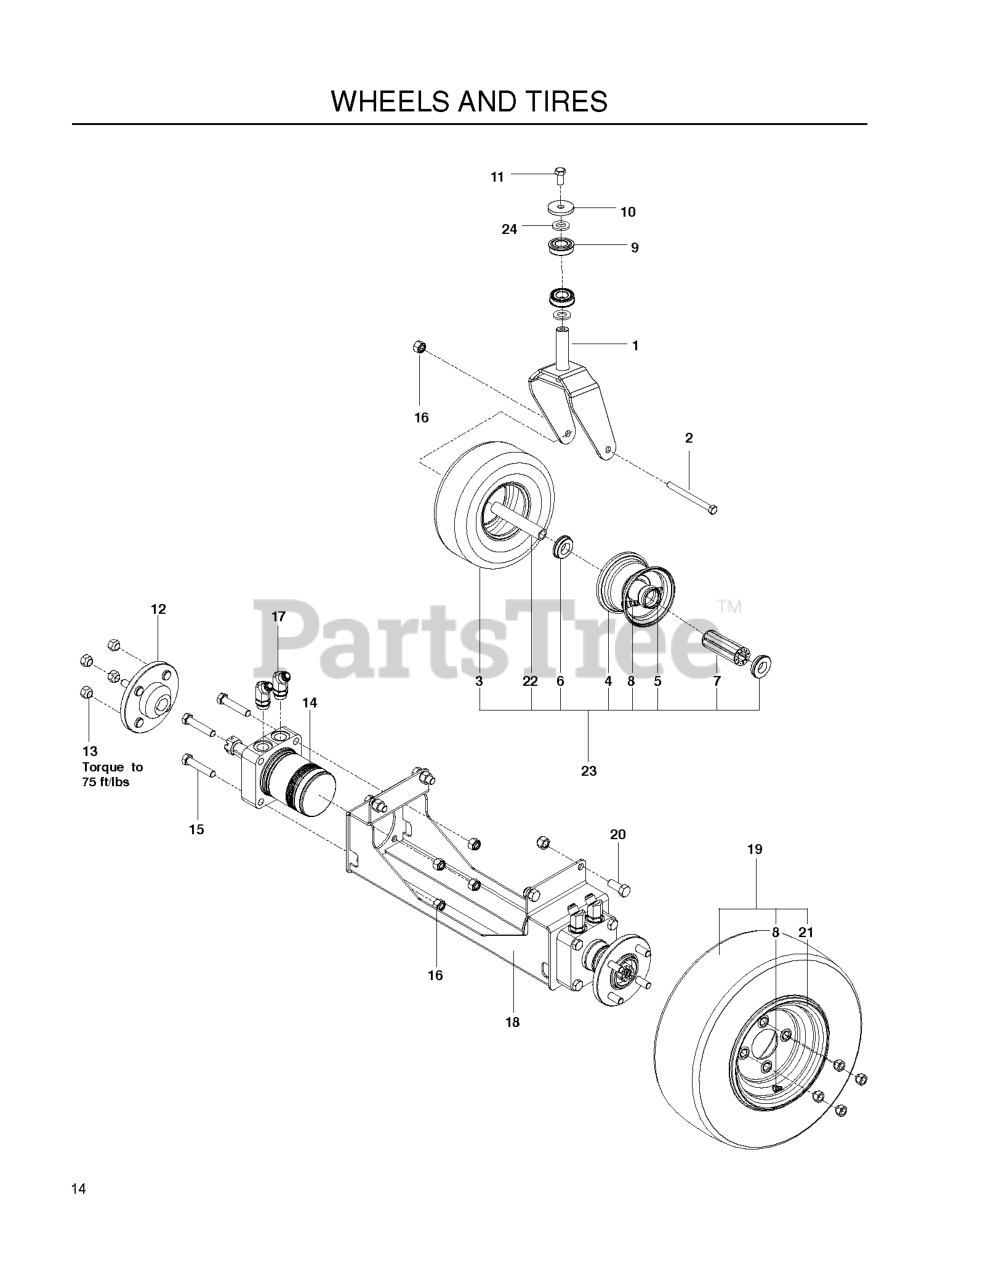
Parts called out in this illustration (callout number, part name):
1	CASTER YOKE - PAINTED
2	HCS 1/2C X 5 1/2
3	TIRE - CASTER
5	ZERK
6	BEARING RETAINER
7	ROLLER BEARING-CAGED 3 1/4'
8	VALVE STEM TR-412
9	BEARING 1" X 2"
10	HEAVY WASHER
11	HHCS 1/2-13 X 1
12	HUB, WHEEL
13	LUG NUT 1/2F
14	WHEEL MOTOR
15	HEX SCREW 1/2-13 X 2.5" GR 5
16	NUT 1/2-13 HEX NYLOC ZD
17	45 DEG STRAIGHT THD ELBOW 8-10
19	WHEEL ASSY, 18 X 6.50-8
20	HCS 1/2-13 X 1-1/4
23	TIRE/WHEEL.CASTER
24	MACHINE BUSHING
